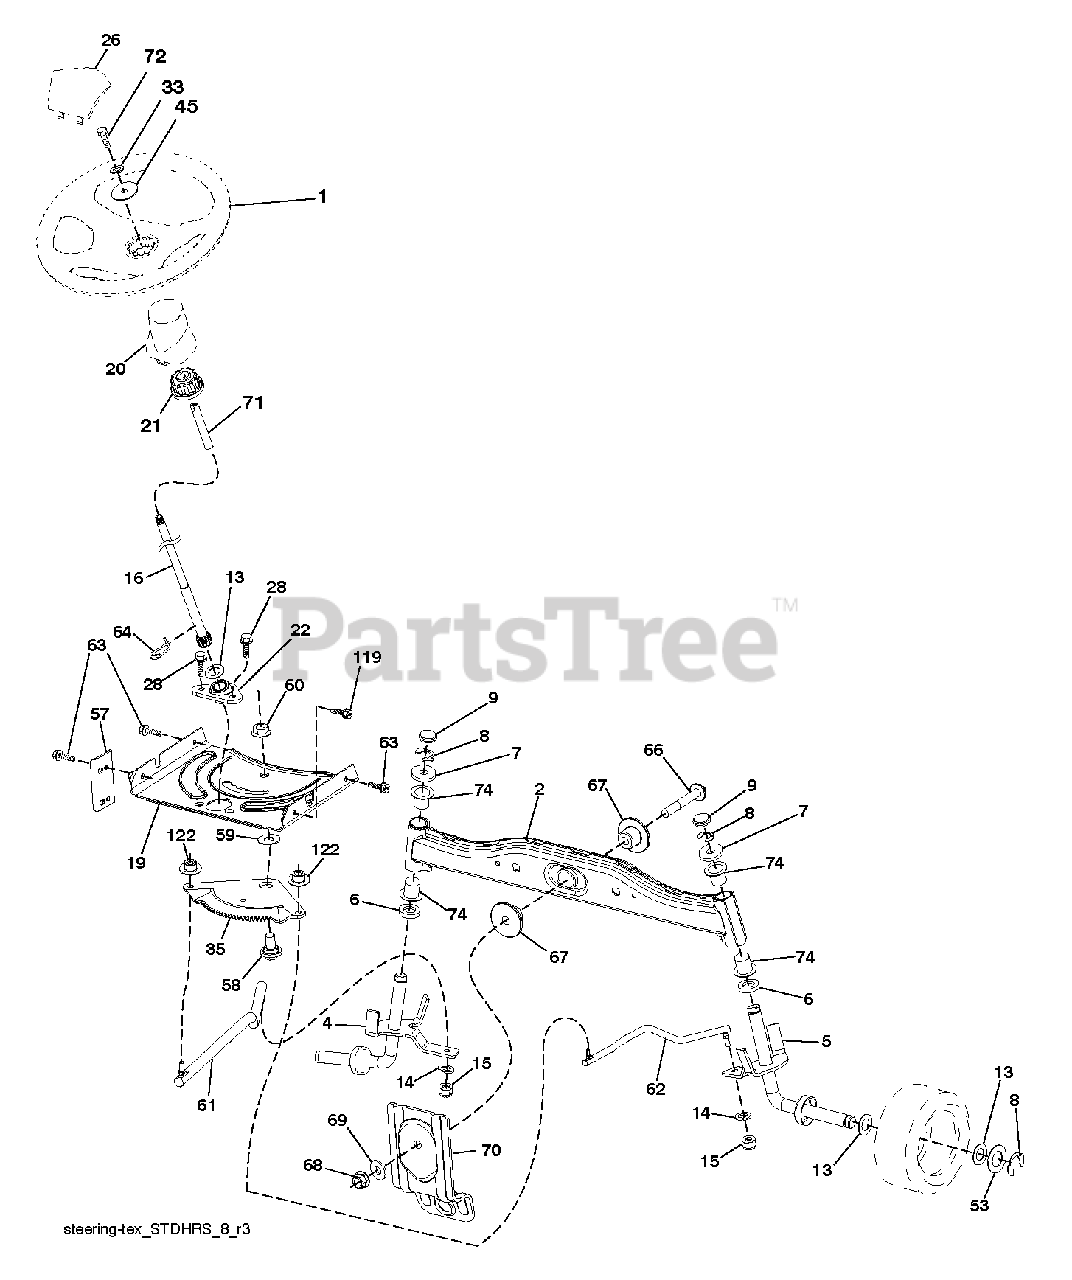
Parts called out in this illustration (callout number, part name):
1	WHEEL.STEER.HUSQ.SR.498.OVMLD
2	AXLE HALF ASM-WELDED
4	SPINDLE.STEERING.ASM.LH.13".TI
5	SPINDLE.STEERING.ASM.RH.13".TI
6	THRUST WASHER
9	CAP.SPINDLE.BLACK
14	WASHER, LOCK 3/8
15	NUT CROWNLOCK 3/8-24
16	SHAFT.STEER.3/4.PLATED.TEX
19	PLATE.STEER.DDL.NLT/NG
20	STEERING.BOOT.HUSQ.LT
21	ADAPTER, WHEEL STNG..
22	STEERING.SUPT.LOWER.
26	INSERT.CAP.WHL.STRG.HUSQ.PREM
28	SCREW, 3/8-16X3/4
33	LOCKWASHER
35	GEAR.SECTOR.PLATE.DDL.
45	WASHER.11/32
53	WASHER.HARDENED
57	BRACKET.UPSTOP.TEX
58	BOLT.SHOULDER.SECTOR.P
59	WASHER.THURST.SECTOR.S
60	NUT FLANGE LOCK 5/8-11
61	DRAGLINK.LH.BALLSTUD.D
62	DRAGLINK.RH.BALLSTUD.D
63	SCREW
64	RETAINER.CLIP.SPRING.S
66	BOLT HEX FGHD 7/16-14 X 3 SERR
67	BUSHING.PM.FRONT AXLE
68	NUT.LOCK.FLANGE.7/16
69	WASHER.1.5X.505X.118
70	BRACKET.SUSP.MWR.FRT.30"SRD
71	SHAFT.EXTEN.STRG.SPLINE
72	BOLT 5/16-18 X 4 W/PATCH
74	BRNG T
119	SHOULDER BOLT 5/16-18TT
122	CAP.GEAR.SECTOR.TEX
